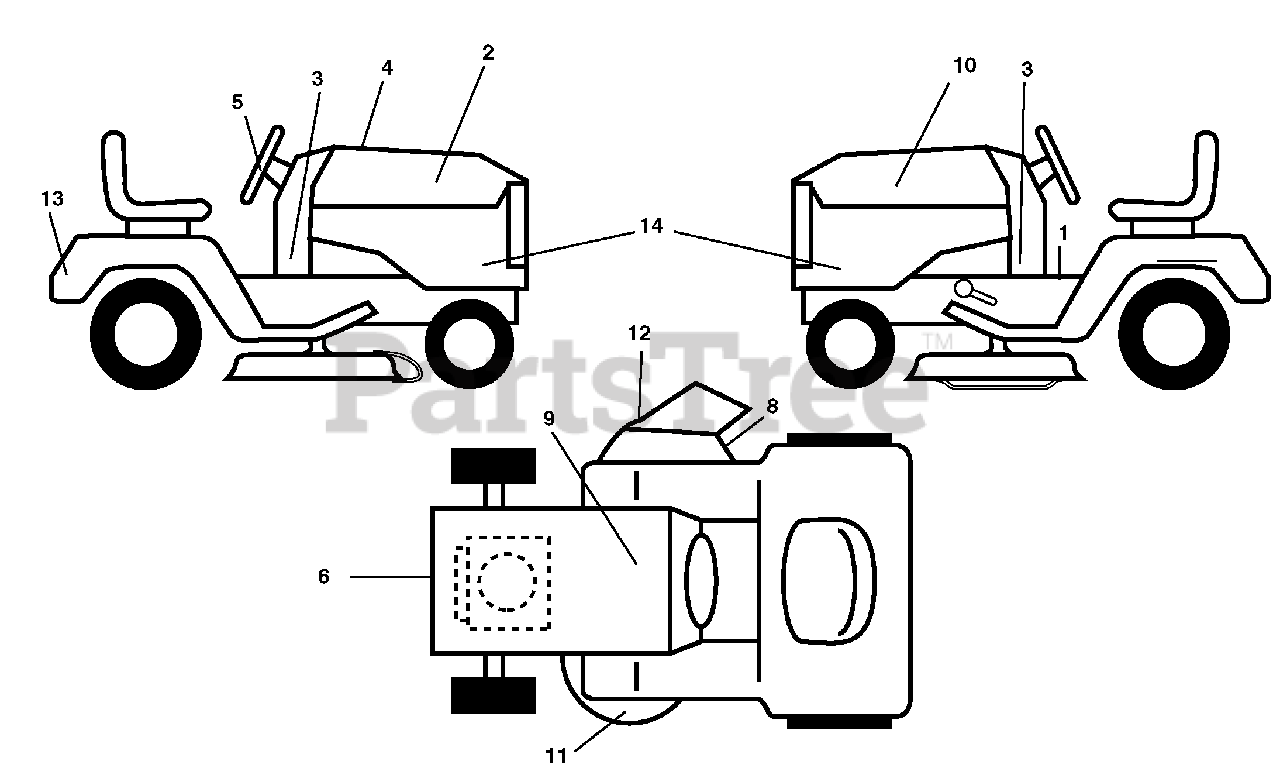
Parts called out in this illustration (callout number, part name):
1	Decal, Operator's
2	Decal, Hood RH
3	Decal, Dash LWR
4	Decal, Replacement
5	Decal, Strg Whl
6	Decal, Engine HP
8	Decal, Mower Sch.
9	Decal, Battery Dnge/Poi
10	Decal, Hood LH
11	Decal, Mower Caution
12	Decal, Mower Warning Keep Hand Away
13	Decal, Fender
14	Decal, Panel SD
14	Decal, Bypass
14	Pad, Footrest, LH
14	Pad, Footrest, RH
14	Manual, Operator's (Eng & French)
14	Manual, Parts
